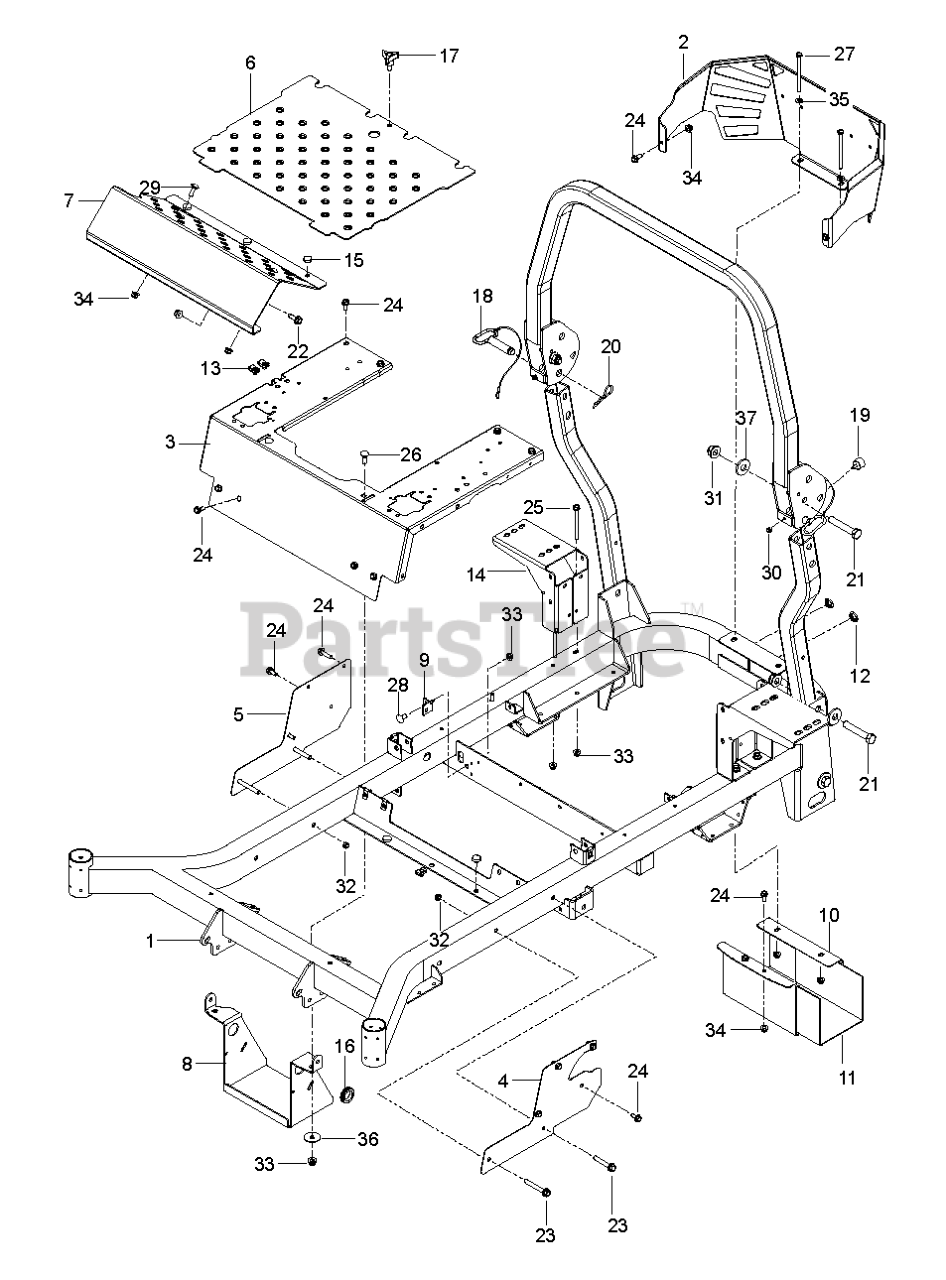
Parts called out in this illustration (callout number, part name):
1	FRAME.KIT.W/DECALS.REDMAX.672
2	GUARD.REAR.PAINT.SNAP.RED.672
3	SUPPORT SEAT CONTROL SNAPPER R
4	BRACKET SIDE LH SNAPPER RED X6
5	BRACKET SIDE RH SNAPPER RED X6
6	KIT.PLATE.FLOOR.W/DCL.REDM.672
7	PLATE.FOOTREST.PNT.G-BLACK
8	PLATE.FOOTREST.PNT.G-BLACK
9	BRACKET.DAMPENER.BLACK
10	SHIELD.MUFFLER.BLACK
11	HEAT SHIELD
12	CAP.PLUG.BP-1.BLACK
13	U-CLIP 5/16-18 NUT RETAINER
14	MOUNT, TANK, ZT BLK
15	GROMMET, BUMPER
16	RUBBER GROMMET
17	KNOB W/STUD
18	PIN, ROPS
19	BUMPER, MALE STUD, 1/4-20
20	PIN HAIR .148 X 2-15/16 #210
21	5/8-11 X 3-1/2 HHB GRADE 5
22	RP BLT 5/16-18 X 1 THRD FORM D
23	HHFS 3/8-16 X 2-3/4 GR5 ZD
24	HHFS 5/16-18 X 3/4
25	BOLT.HEX.FLNG.5/16-18X3.75
26	RHSNB 3/8C X 1
27	HCS 5/16C X 4
28	RHSNB 3/8-16 X 3/4 GR 5 BLK ZN
29	RHSNB 5/16C X 1
30	RP_NUT 1/4-20 NYLOC
31	NUT 5/8-11 FLG NYLOC ZD
32	NUT HEX 3/8-16 NYLON, THIN
33	NUT 3/8-16 HEX FLG NYLOC ZD
34	5/16-18 NYLOC FLANGE NUT
35	WASHER
36	WASHER.13/32X1-1/2X16GA
37	WASHER, 5/8 FLAT
